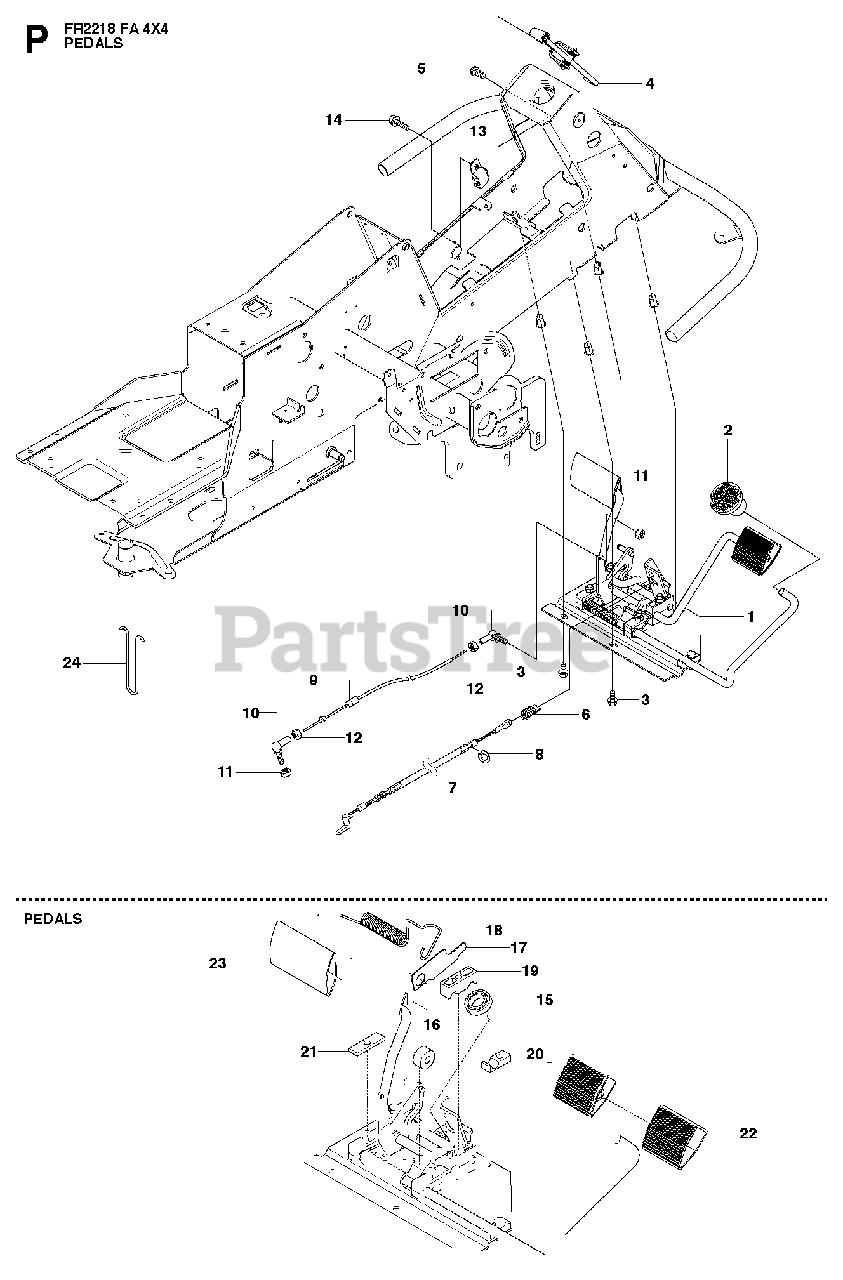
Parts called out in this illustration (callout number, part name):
1	PEDAL ASSEMBLY
2	KNOB
4	BRAKE LEVER ASSY
7	RP WIRE
9	CONTROL CABLE
10	CONNECTOR
11	LOCKNUT M5
15	BALL BEARING 6002-2RS1
16	ROLLER
17	PLATE
18	SPRING
19	PEDAL SHAFT CLAMP
20	SUPPORT
21	PLATE
22	PEDAL RUBBER
23	PEDAL RUBBER, SF
24	CABLE HOLDER
